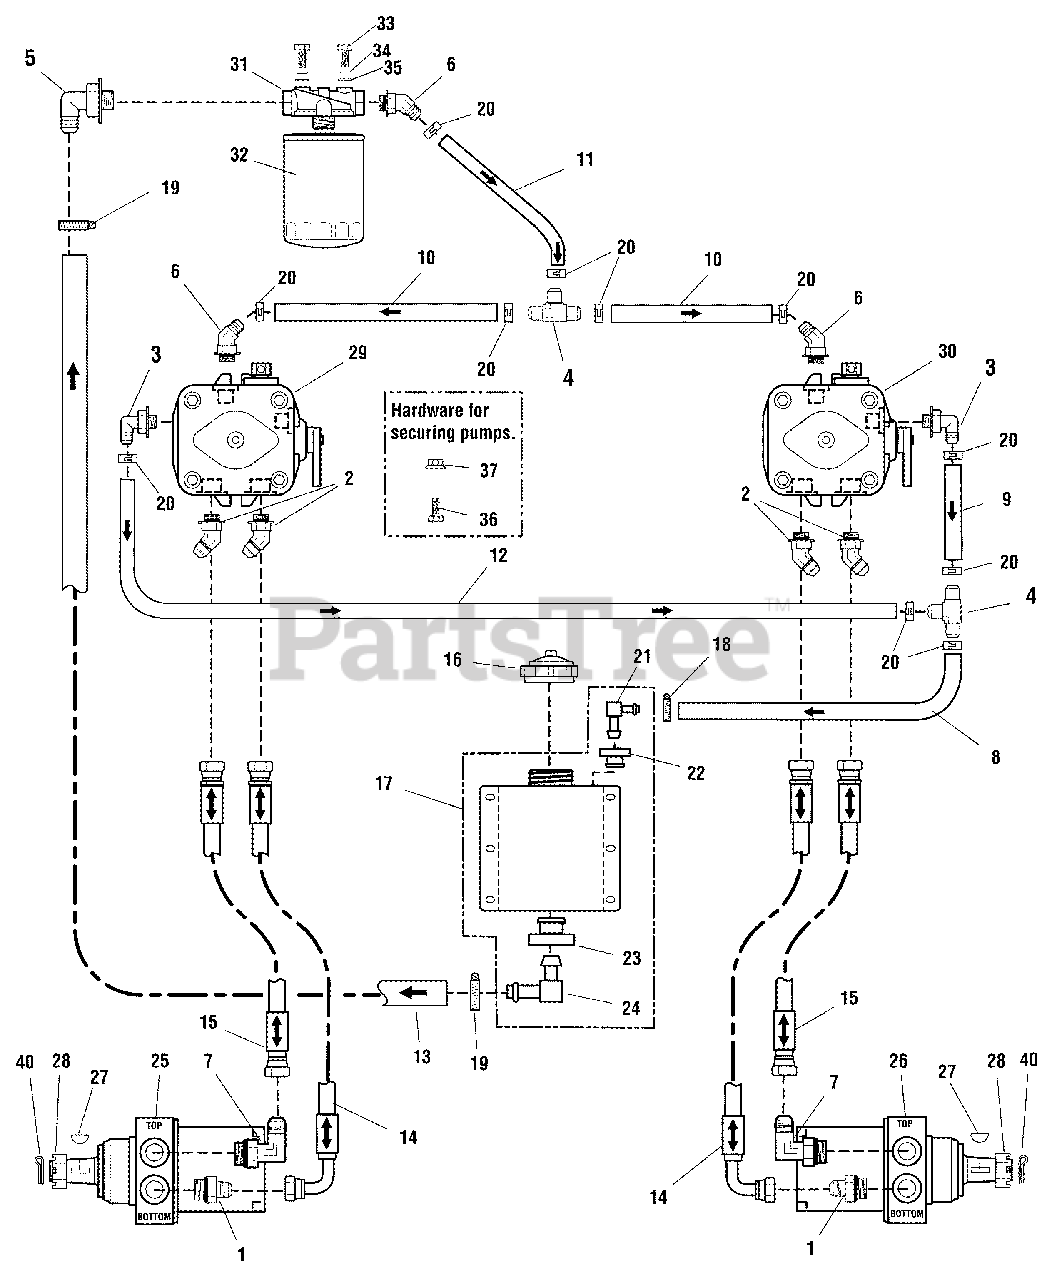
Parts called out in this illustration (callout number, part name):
1	ADAPTER, HYDRAULIC
2	FITTING, #8 JIC - #8 O-RING 45DEG.
3	ADAPTER, 90 DEG. 9/16 - 3/8 BARB
4	FITTING, TEE, 1/2" HOSE
5	ADAPTER, 90 DEG. 9/16 - 5/8 BARB
6	ADAPTER, 45, 9/16 - 3/8 BARB
7	FITTING, #10 ORING-#8 JIC, 90D
8	HOSE, 3/8" PUSH-LOCK, 18.00"
9	HOSE, 3/8" PUSH-LOCK, 6.50"
10	HOSE, 3/8" PUSH-LOCK, 6.00"
11	HOSE, 3/8" PUSH-LOCK, 8.00"
12	HOSE, 3/8" PUSH-LOCK, 23.00"
13	HOSE, 5/8" PUSH-LOCK, 24.00"
14	HOSE ASSEMBLY, 26.50"
15	HOSE ASSEMBLY, 22.50"
16	CAP, HYDRAULIC
17	TANK, HYDRAULIC, ASSEMBLY
18	CLAMP, #4 HOSE, STAINLESS
19	CLAMP, #10 HOSE, STAINLESS
20	CLAMP, HOSE
21	FITTING, ELBOW, 3/8"
22	GROMMET
24	FITTING, ELBOW, 5/8"
25	WHEEL MOTOR, LH, 14.5 CUBIC INCH
26	WHEEL MOTOR, RH, 14.5 CUBIC INCH
28	NUT, CASTLE, 1-20
29	PUMP, HYDROGEAR 12CC - LH
30	PUMP, HYDROGEAR 12CC - RH
31	FILTER HEAD, HYDRAULIC
32	FILTER, OIL
33	BOLT, 1/4"-20 X 3/4" GD5 YZ
34	WASHER, 1/4 SAE (5025154)
35	WASHER, 1/4" LOCK
36	BOLT, 3/8-16 X 1-1/4" GD5
37	NUT, 3/8-16 HEX SERRATED FLANGE
40	PIN, COTTER, 1/8" X 2"
